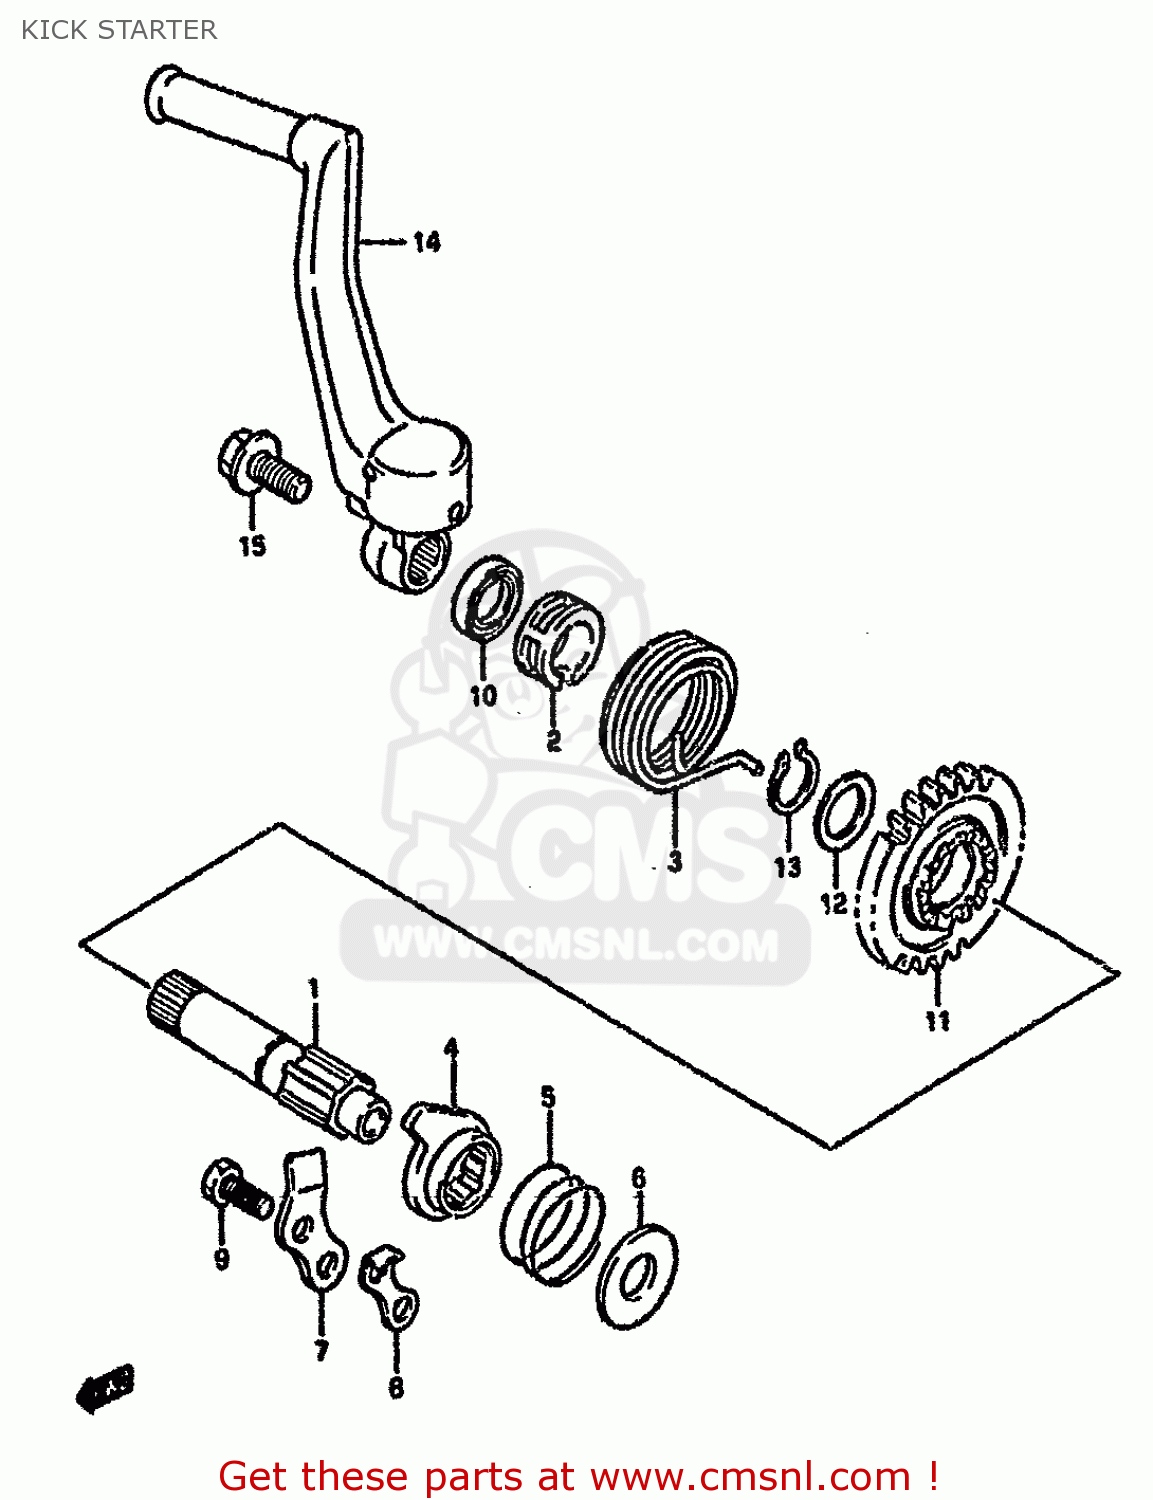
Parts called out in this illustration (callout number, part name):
1	SHAFT,KICK STARTER
2	GUIDE,KICK STARTER SFT SPRING
3	SPRING
4	STARTER,KICK
5	SPRING
6	WASHER
7	GUIDE,KICK STARTER
8	STOPPER,KICK STARTER
9	BOLT
10	SEAL,OIL(16X24X5)
11	GEAR,KICK STARTER DRIVE
12	WASHER
13	CIRCLIP 16MM
14	LEVER ASSEMBLY,KICK STARTER
15	BOLT(8X14)
